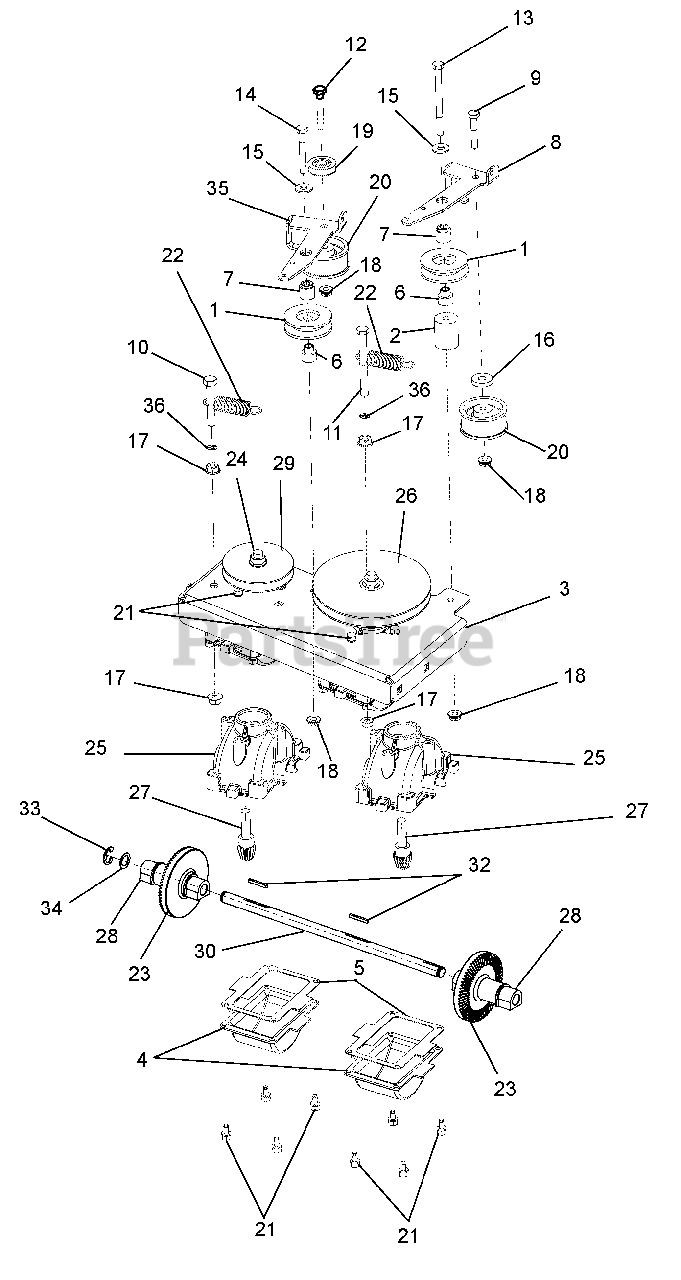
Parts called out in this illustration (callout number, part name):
1	Idler, 3L Front Side .38 x 1.875
2	Spacer, Reverse Idler
3	Plate, Transmission Mount
4	Sump, Gearbox
5	Gasket, Transmission
6	Spacer, Idler Pulley
7	Spacer .390 x .75 x .189
8	Bracket, Transmission Idler Arm
9	Bolt, Hex .25-20 x 1.50
10	Bolt, Hex .31-18 x 2.00
11	Bolt, Hex .31-18 x 3.50 Grade 5
12	Bolt, Hex .25-20 x 1.75
13	Bolt, Hex .25-20 x 3.25
14	Bolt, Hex .25-20 x 2.00
15	Washer, Flat Steel .312 x .734 x .065
16	Washer, Flat Steel .38 x .87 x .179
17	Nut, Spin Lock Flange .312-18
18	Nut, Locking Top Flange .25-20
19	Pulley, Cable
20	Pulley, Idler .25 x 1.87 x .97
21	Screw, Tapping 10-24 x .375 Pre-Coat
22	Spring, Tension .063 x .625 x 2.50
23	Gear, Bevel
24	Nut, Top-Locking Flange .38-16
25	Housing, WAW Gearbox
26	Pulley, Reverse Input
27	Pinion, Gearbox Input
28	Bushing, Transmission Output Shaft
29	Pulley, Transmission Input
30	Shaft, Transmission Output
31	Kit, WAW Transmission (Includes transmission shaft and items 3, 4, 5, 21, 23, 24, 25, 26, 27, 28, 29, 32, 33, 34)
32	Key, 1/8 x 1/8 x 1.0
33	Ring, Retaining-External .500 x .042
34	Washer, .500 x .750 x .020 Thrust
35	Arm, Forward Idler
36	Nut, Push .312
